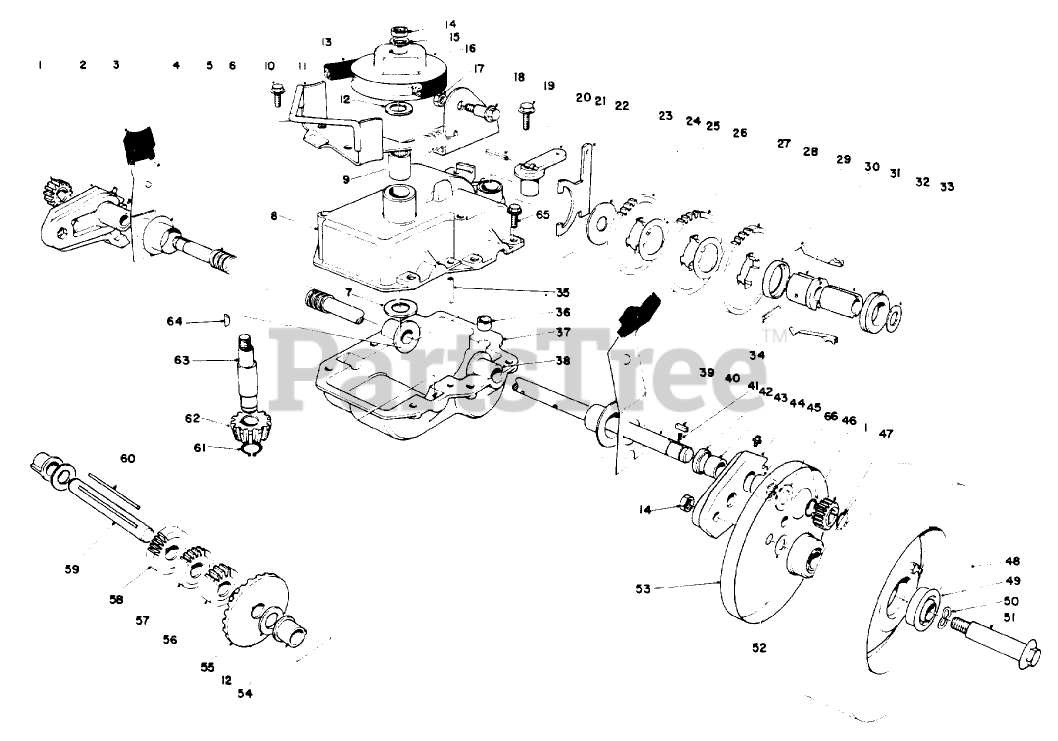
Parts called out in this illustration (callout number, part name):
1	GEAR-PINION
3	KNOB-ARM
5	CAP-END
6	CONDUIT-CONVOLUTED, SPLIT
8	DISC PRC4
12	WASHER-THRUST
13	V-BELT
15	WASHER-FLAT
16	PULLEY
18	SHOULDER BOLT
19	SCREW-THD ROLL, HWH
20	PIN-SPRING
21	LEVER-SHIFT
23	WASHER
24	GEAR-38T
25	WASHER
27	GEAR-42T
31	SLEEVE
32	COLLAR-SHIFT
33	WASHER-PLAIN
35	ROLL PIN 3/16 X 1 IN
36	BUSHING-YOKE
40	KEY RECTANGULAR
41	SPRING-COMPRESSION
43	Bushing
46	RING-EXT GRIP
47	RING-RETAINING
49	BEARING-BALL
50	SPRING WASHER
51	WHEEL BOLT
52	WASHER
56	14 T GEAR
58	GEAR-18T
61	RING-RETAINING
62	PINION-BEVEL
64	KEY-WOODRUFF
65	SCREW-HWH, THREAD ROLL
